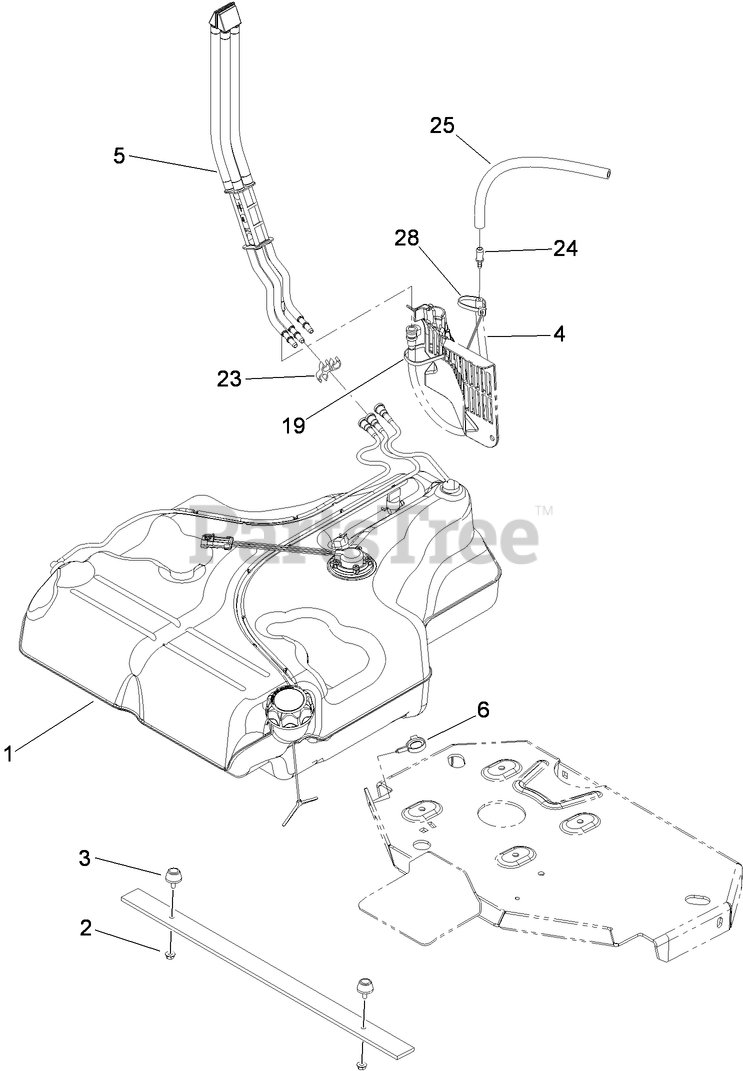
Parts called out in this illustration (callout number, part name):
1	FUEL TANK ASM
2	NUT-HF
3	BUMPER-RUBBER
4	HOSE ASM
5	FUEL MANIFOLD VENT ASM
6	CLAMP-HOSE
19	TIE-PLASTIC
23	CLIP-SPACER
24	FITTING-STRAIGHT
25	HOSE-FUEL
28	TIE-PLASTIC
